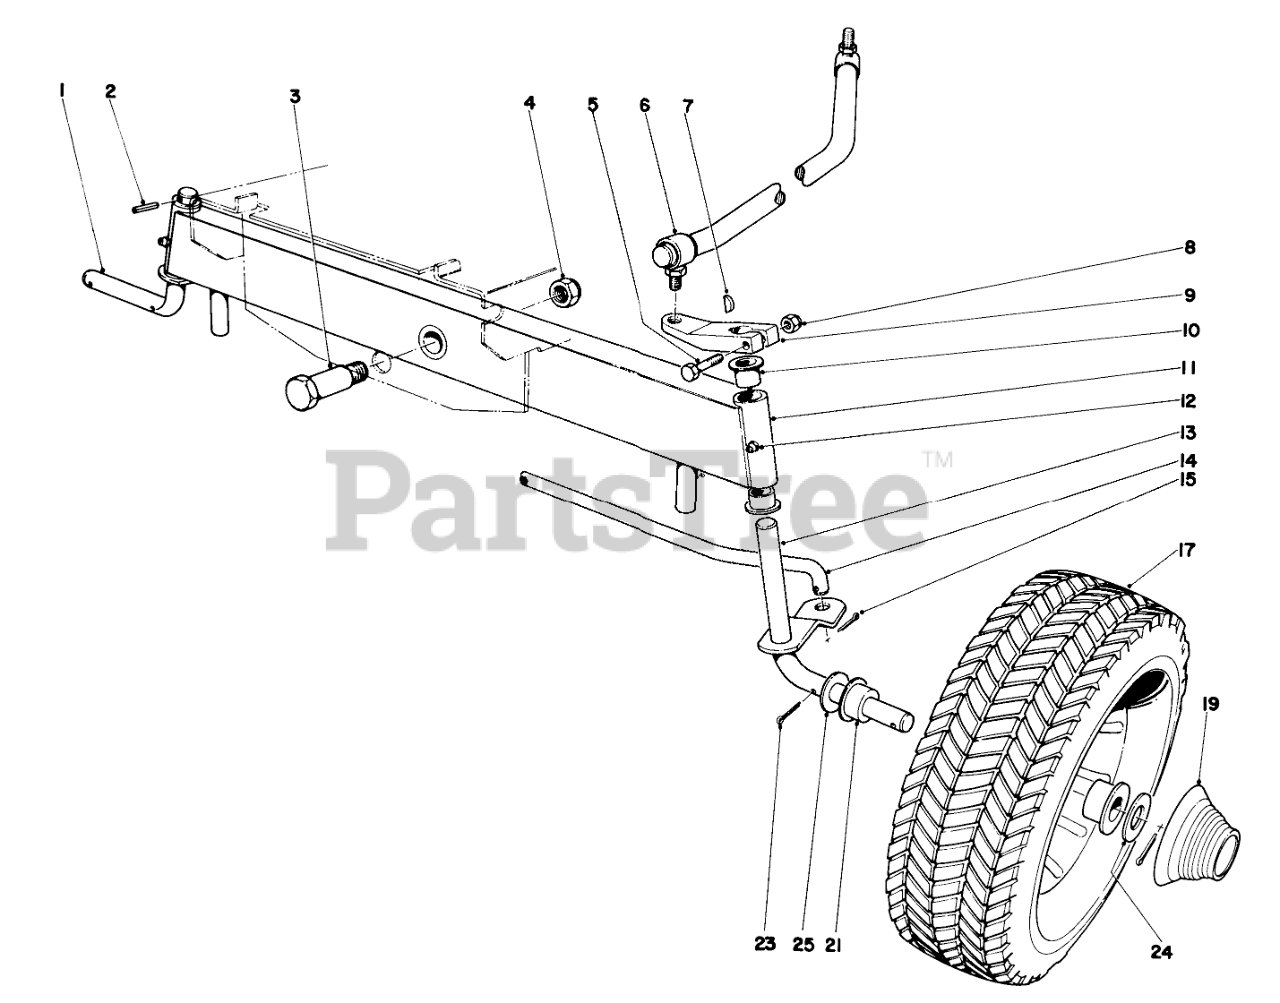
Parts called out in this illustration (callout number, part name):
1	Spindle
2	PIN-SPRING
3	Shoulder Bolt
5	SCREW-HH
6	Steering Rod
7	KEY-WOODRUFF
9	Arm Steering
10	BUSHING-FLANGE
11	Front Axle
12	GREASE FITTING
13	Spindle
14	Tie Rod
15	PIN-COTTER
17	Front Wheel Assembly
19	Hub Cap Front
21	Bushing
23	PIN-COTTER
24	Flat Washer
25	Washer
